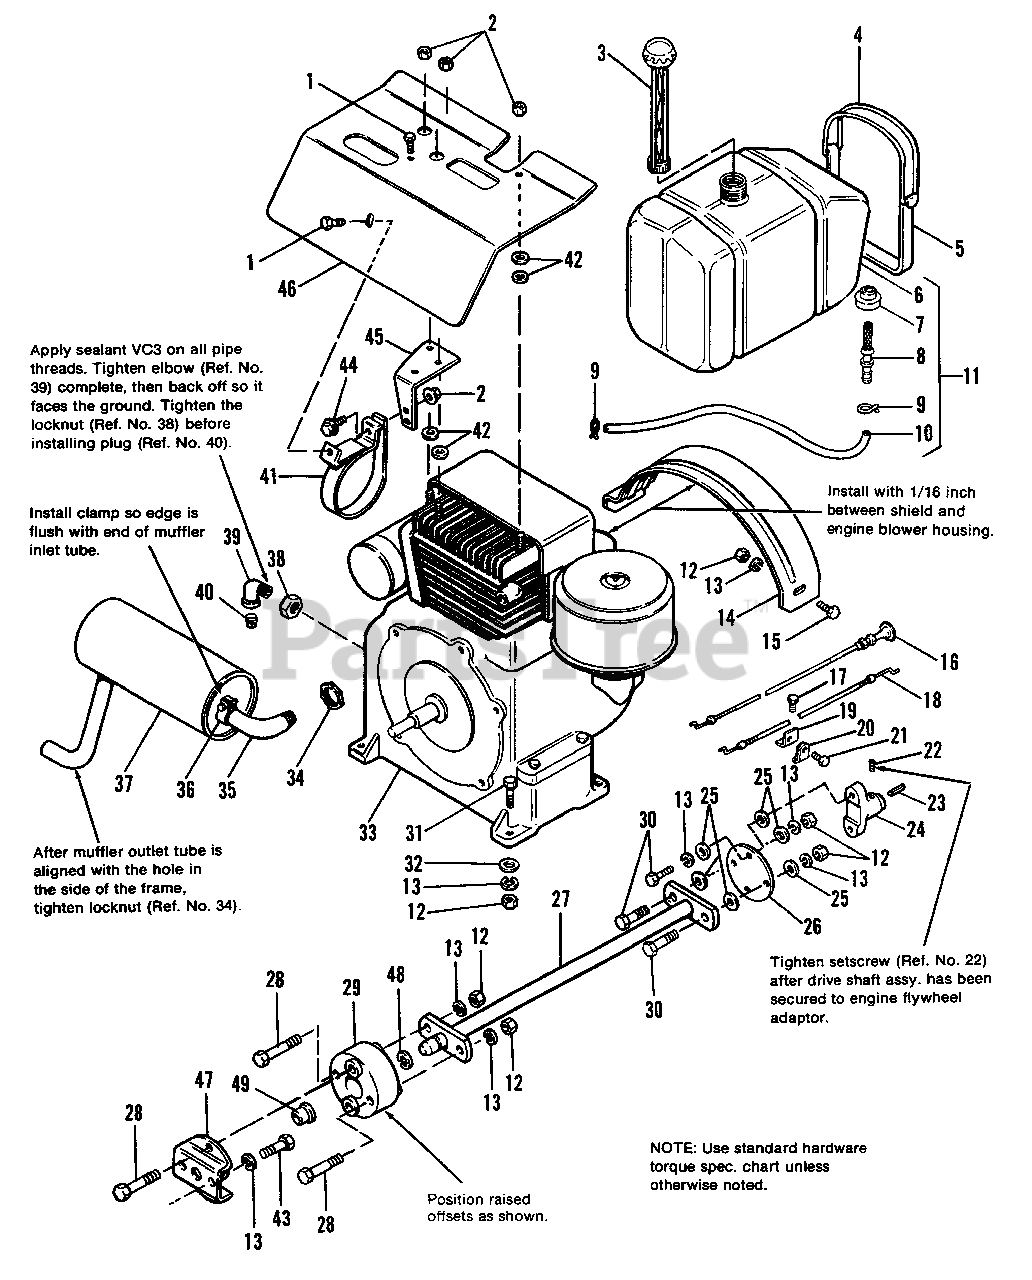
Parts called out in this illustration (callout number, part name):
1	SCREW, Hex, Taptite, 1/4-20 x 1/2
2	NUT, Hex, Whizlock, 5/16-18
3	CAP, Fuel Tank
4	STRAP, Fuel Tank
5	STRAP, Fuel Tank
11	TANK ASSY., Fuel
12	NUT, Hex, Full, 3/8-16
13	LOCKWASHER, 3/8
15	CAPSCREW, Hex Hd., 3/8-16 x 1
16	CONTROL, Choke
17	SCREW, Hex Hd., Type F, 1/4-20 x 5/8
18	CONTROL, Throttle
19	BRACKET, Cable
20	CLIP, Bowden Wire
21	SCREW, Hex, Taptite, #10-24 x 1/2
22	SETSCREW, 3/8-24 x 3/8
23	KEY, Drive Shaft
24	FLANGE, Drive Shaft
25	WASHER, Special
27	SHAFT ASSY., Drive
28	CAPSCREW, Hex Hd., 3/8-16 x 2-1/2
29	COUPLING, Compression
30	CAPSCREW, Hex Hd., 3/8-16 x 1-1/4
31	CAPSCREW, Hex Hd., 3/8-16 x 1-1/2
32	WASHER, Plain, 3/8
33	ENGINE, 16 HP Briggs & Stratton
35	ELBOW ASSY., Exhaust
36	CLAMP, Muffler
37	MUFFLER, Exhaust
38	LOCKNUT, 3/8-18
39	ELBOW, 90ø, 3/8
40	PLUG, Pipe, Hex
41	STRAP ASSY., Muffler
42	WASHER, Plain, 5/16
43	CAPSCREW, Hex Hd., 3/8-16 x 7/8
44	CAPSCREW, Whizlock, 5/16-18 x 1-1/2
45	SUPPORT, Muffler
46	SHIELD, Heat
47	PLATE ASSY., Adaptor
48	RING, Retaining
